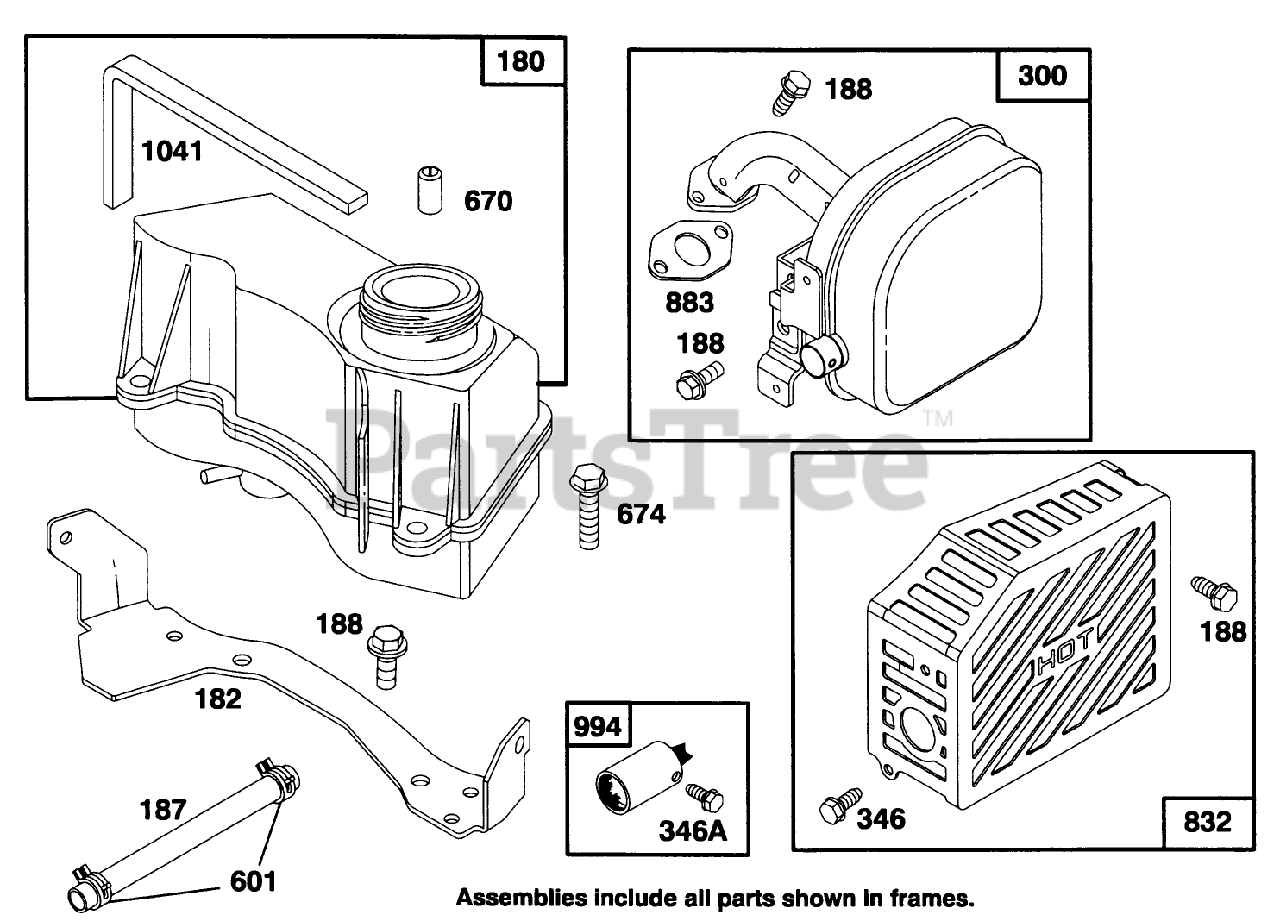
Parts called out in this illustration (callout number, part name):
180	TANK ASSY - FUEL
188	SCREW - SEM
300	MUFFLER - EXHAUST
346	SCREW - SELF-TAPPING
601	CLAMP - CL PIPE
670	SPACER
674	SCREW - HEX HEAD
